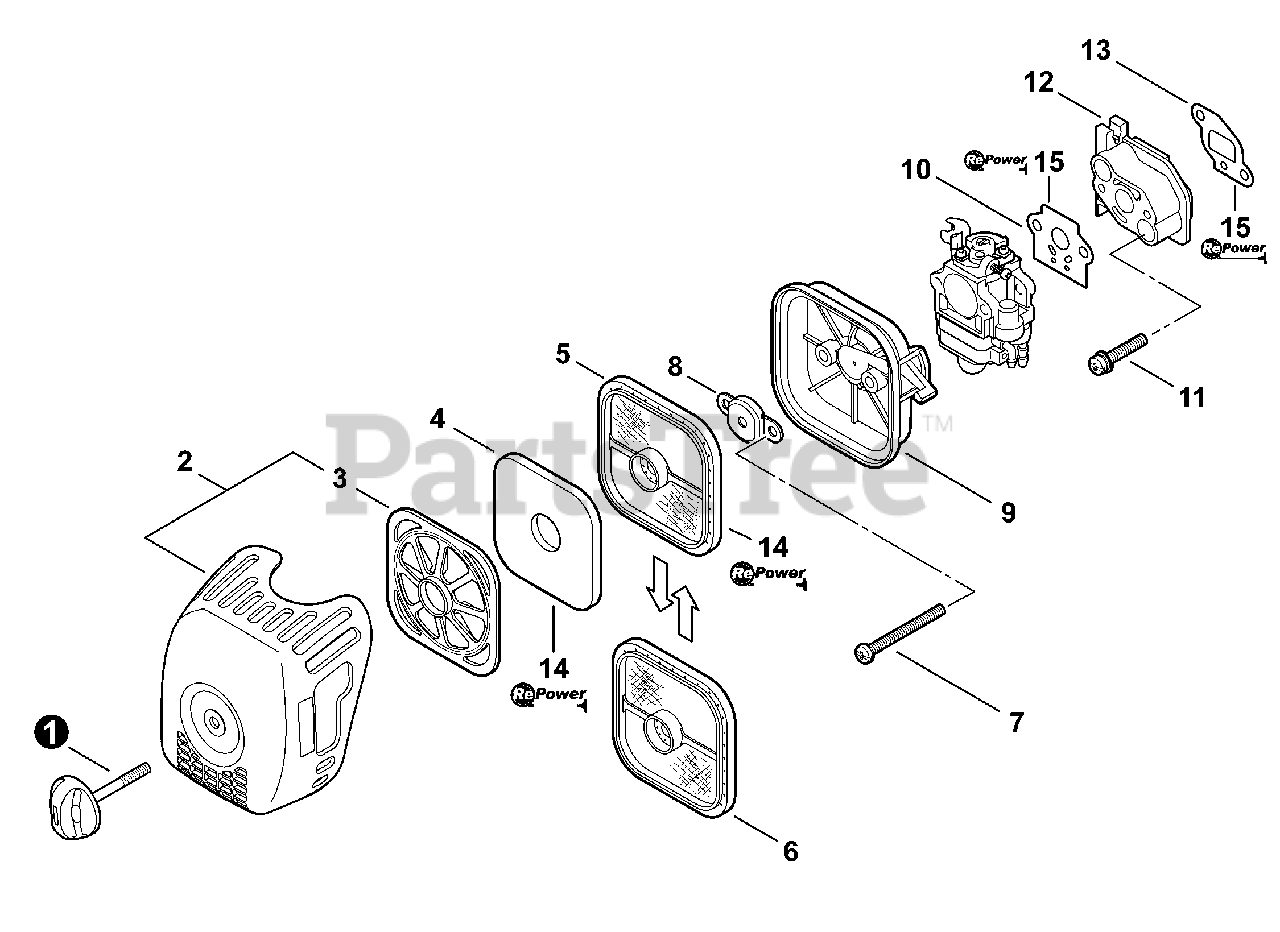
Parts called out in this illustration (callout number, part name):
1	THUMBSCREW
2	COVER KIT, AIR FILTER
3	RETAINER, PRE-FILTER
4	PRE-FILTER, FOAM
5	FILTER, AIR - DOUBLE LAYER
6	FILTER, AIR - SINGLE LAYER
7	SCREW 5×60
8	PLATE, PREVENT
9	CASE, AIR FILTER
10	GASKET, INTAKE
11	BOLT 5×30
12	INSULATOR, INTAKE
13	GASKET, INTAKE
14	TUNE-UP KIT - REPOWER
15	GASKET KIT
